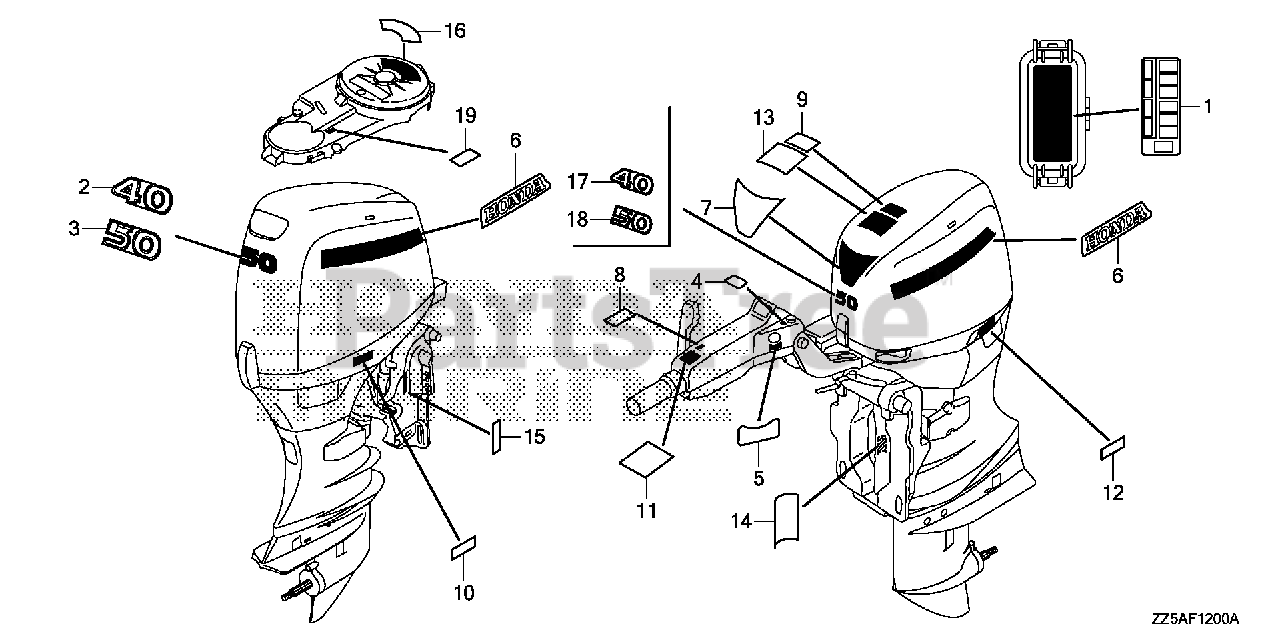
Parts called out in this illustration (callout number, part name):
1	LABEL, FUSE
2	MARK, RR. (40)
4	MARK, EMERGENCY SWITCH INDICATION (EU)
5	MARK, STARTER (ENGLISH)
6	MARK, SIDE STRIPE
8	MARK, CHANGE
11	MARK, THROTTLE (ENGLISH)
12	LABEL, STORING CAUTION (ENGLISH)
13	LABEL, WARNING OPERATOR (ENGLISH)
14	LABEL, ASSIST TILT CAUTION (ENGLISH)
15	MARK, ASSIST LEVER (ENGLISH)
16	MARK, EMERGENCY START (ENGLISH)
17	MARK, FR. EMBLEM (40)
19	LABEL, CAUTION OIL
